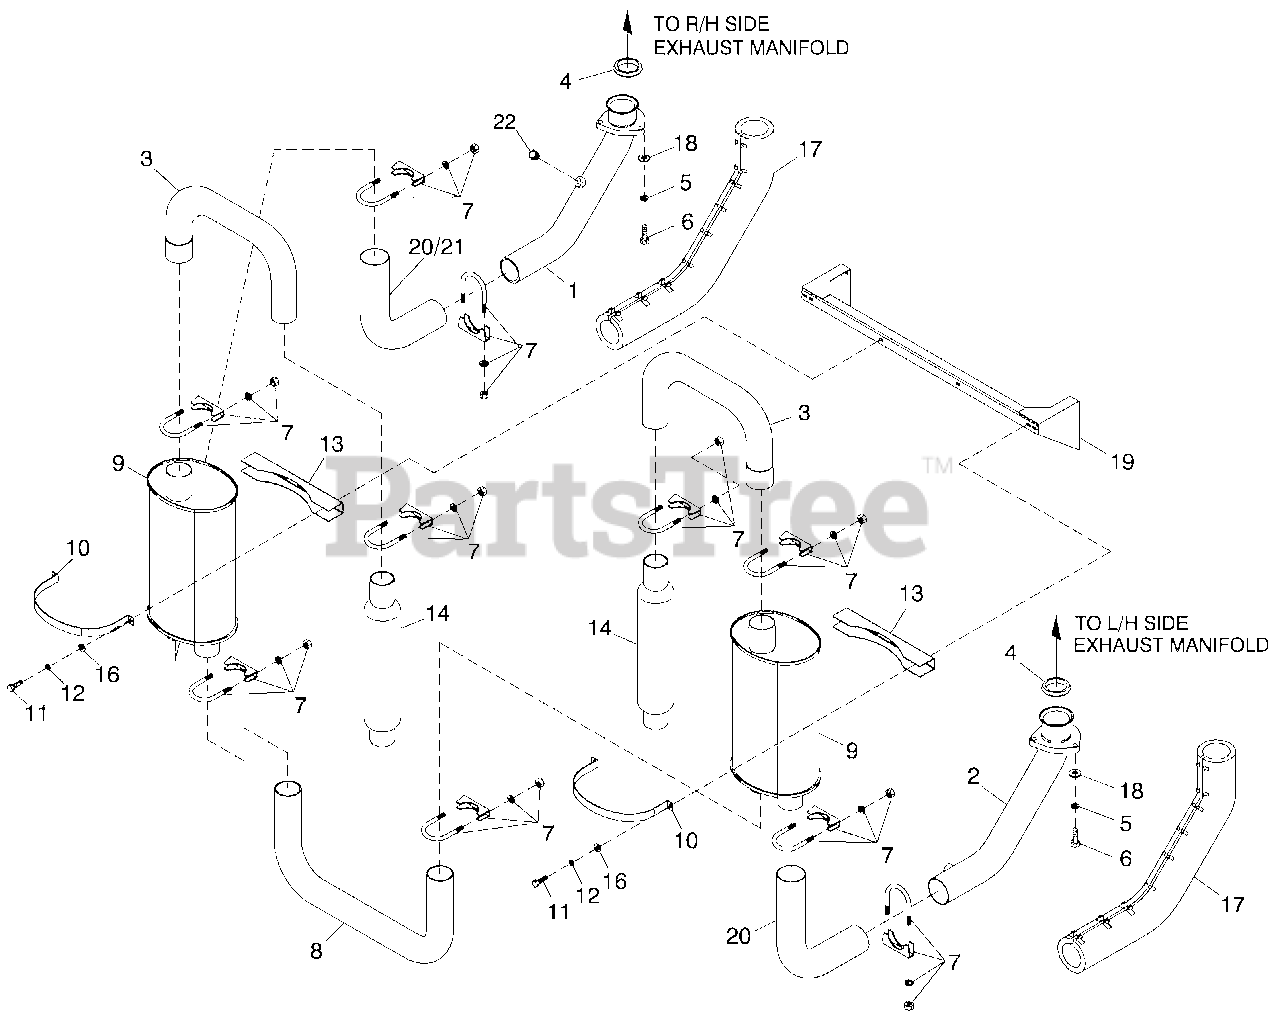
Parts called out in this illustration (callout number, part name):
1	PIPE EXH MANIFOLD 6.8L C3 RH (6.8L 70KW)
2	PIPE EXH MANIFOLD 6.8L C3 LH (6.8L 70KW)
3	PIPE EXHAUST MUFFLER OUT
4	RING GASKET, 2.5DIA
5	WAS HER LOCK M10SS
6	SCREW HHC M10-1.5 X 50 S S FTH
7	BOLT U 3/8-16X2.62
8	PIPE EXHAUST CROSSOVER
9	MFLR 7" X 9" X 25" (2) 2.5" IN/2.5" OUT
10	MUFFLER STRAP
11	SCREW HHC M6-1.0X 16 G8.8
12	WAS HER LOCK M6-1/4
13	MUFFLER BRACKET STIFFENER
14	GLAS S PACK 23.5" LG 2.5" IN/OUT
16	WAS HER FLAT 1/4-M6 ZINC
17	EXHAUS T BLANKET 800MM LG (6.8L 70KW)
18	WAS HER FLAT 3/8 S S
19	BRKT MUFFLER
20	PIPE LH MUFFLERS IDE
21	PIPE RH MUFFLER SIDE
22	PLUG M18-1.50
